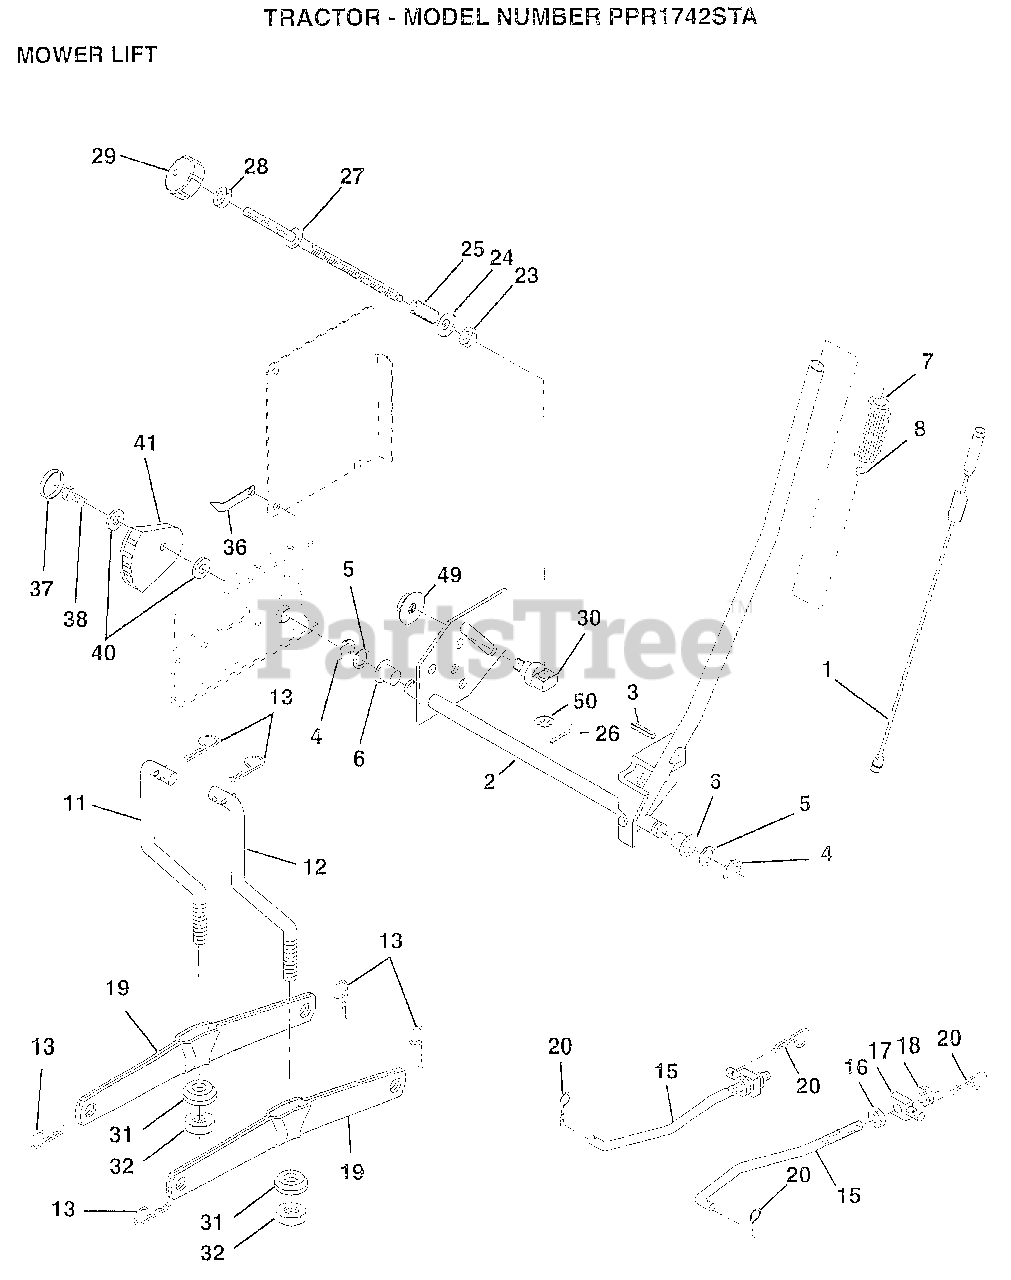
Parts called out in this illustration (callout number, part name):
1	WIRE ASM W.SPRING
2	"SHAFT ASM LIFT,RH"
3	PIN-GROOVE LT
5	WASHER
6	NYLON BEARING
7	GRIP HANDLE
15	LINK.FRONT
16	NUT
17	TRUNION
18	NUT LTV
19	ARM SUSP REAR
20	RETAINER SPRING
23	NUT T
24	WASHER
25	SPRING T
28	NUT
29	KNOB INF 3/8-16
30	TRUNNION
31	BEARING PVT LH
32	NUT.CROWNLOCK.3/8
36	POINTER-INDICAT
37	"PLUG,HOLE"
38	SCREW
40	WASHER
41	INDICATOR HEIGHT
49	NUT.HXFLG.LOCK.
50	NUT PUSH M
